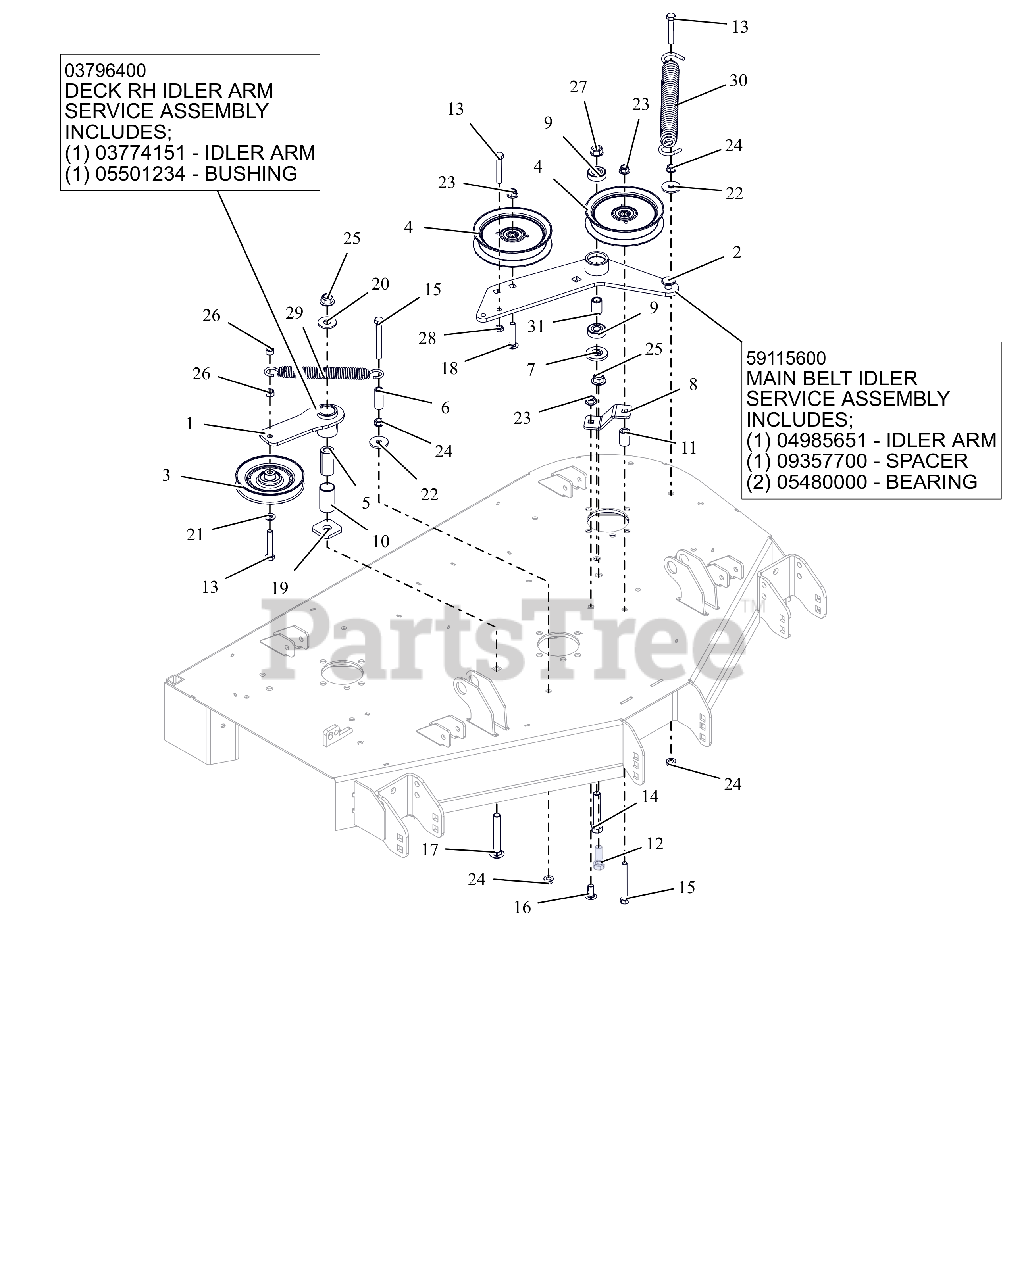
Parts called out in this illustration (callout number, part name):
1	WMT, IDLER ARM - BLACK
1	ASM, IDLER ARM (DECK)
2	DECK PTO IDLER ARM WLDMT - BLK
2	ASSEMBLY, MAIN BELT IDLER
3	IDLER, V-5.00"
4	IDLER, FLAT 5.00"
5	BSHG, SPCR .502X.997X2.03 PM
6	SPACER, .375IDX.625ODX1.66 PM
7	SPACER, IDLER ARM
8	PTO FIXED IDLER MTG BRKT -RED
9	BRG-BALL .500X1.38X.437
10	BSHG, 1.00X1.125X1.937
11	BUSHING, SLV .380X.750X1.190
12	BLT,HEX .50-13X1.50 G5 ZCC
13	BLT,HEX .38-16X2.25 G5 ZCC
14	BLT, HEX .50-13X3.00 G5 ZCC
15	BLT, HEX .38-16X3.25 G5 ZCC
16	BLT,RHSSN .38-16X1.00 G5 ZCC
17	BLT, RHSN .50-13X3.50 G5 ZCC
18	BLT,RHSSN.375-16X2.00 G5 ZCC
19	WSHR-FLT .640X1.75X.250
20	WSHR,FLT .563X1.375X.109 ZCC
21	WSHR,FLT .406X.812X.065 ZCC
22	WSHR,FLT .406X1.375X.135 ZCC
23	NUT,NYL-FLG .38-16 GF ZCC
24	NUT, SPNLK-FLG .38-16 G5 ZCC
25	NUT,NYL-FLG .50-13 GF ZCC
26	NUT-LK-CTR .38-16 ZC120
27	NUT-LK-CTR-FLG .500-13 GG ZCC
28	NUT-JAM .375-16 G2 ZCC
29	SPRING, EXTENSION
30	SPRING, EXTENSION
31	SPACER .510 X .75 X 1.1485
